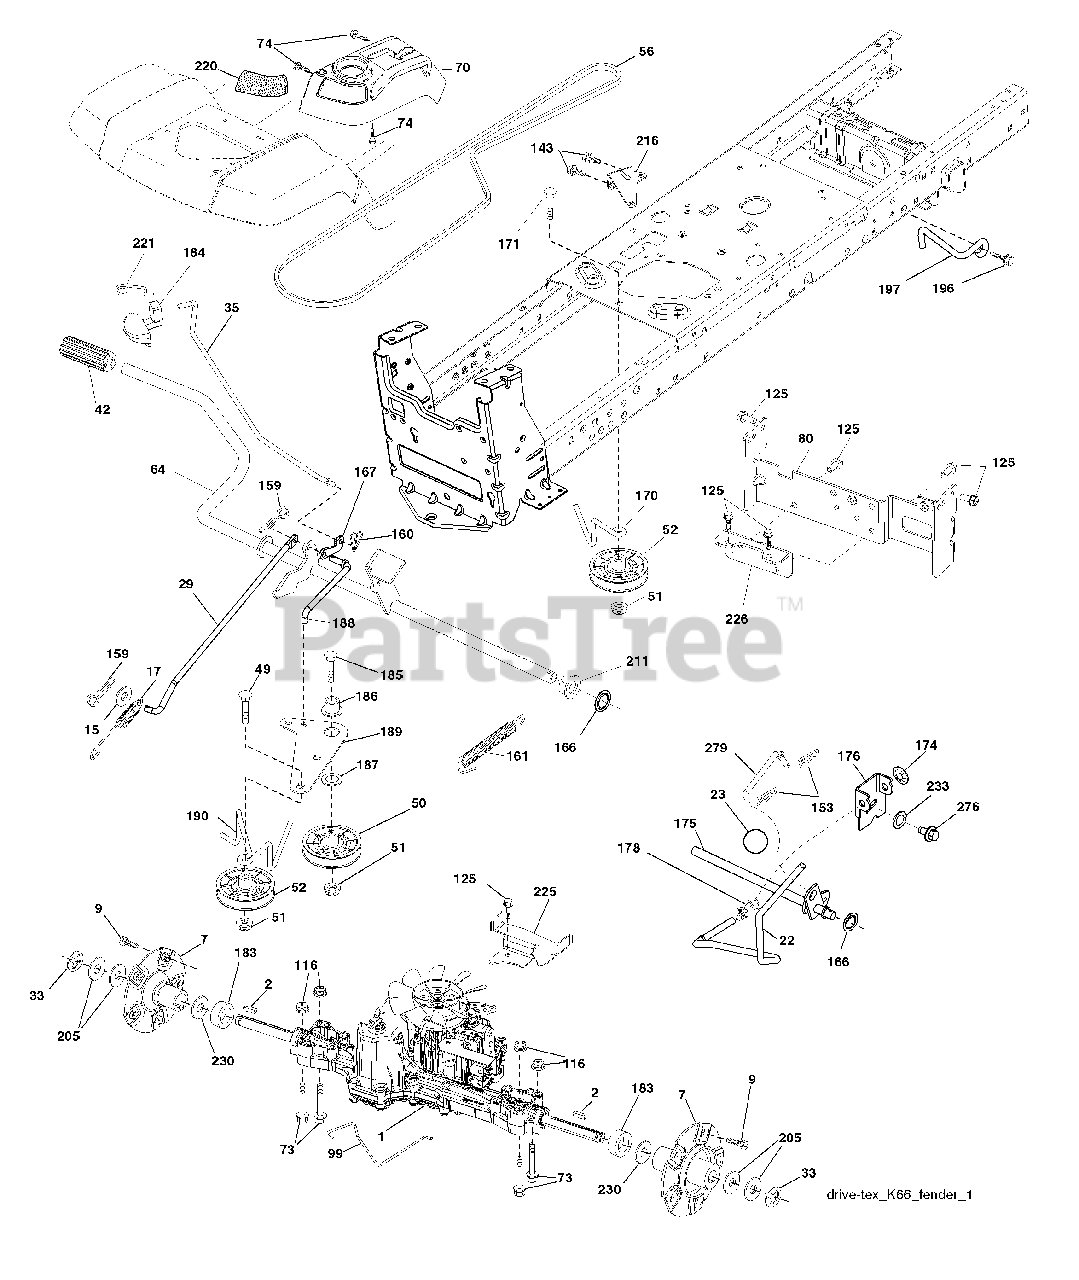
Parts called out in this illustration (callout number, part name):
1	Transaxle, TuffTorq K66
7	Hub Asm. Wheel
9	Bolt Hub Wheel
15	Washer 13/32 x 13/16 x 16 Ga.
17	Spring, Brake
23	Knob Deluxe 1/2-13 unc
29	Rod, Brake
35	Rod, Brake, Park
42	Cover, Foot Pedal
50	Pulley Idler Flat
51	Lock Nut 3/8-16
52	Idler V-Groove 910" Offset
56	V-Belt, Drive
64	Shaft Asm. Pedal Brake Control
70	Console Asm.
73	Bolt Hex Flghd 5/16-18 Gr. 5
74	Screw Hx Wsh Hi-Lo 1/4 x 1/2 unc
80	Strap Torque
99	Rod Bypass
116	Nut Lock Hex Flange 5/16-18
125	Screw 5/16-18 x 3/4
143	Screw 5/16-18 x 1/2
153	Retainer Spring
159	Pin Cotter 1/8 x 3/4
160	Retainer Clip
161	Spring, Return, Clutch
166	Nut Push .625
167	Latch Brake Parking
170	Keeper Belt Centerspan
175	Shaft Asm. Shift
176	Arm Clevis Rod Shift
178	Spring Shift
183	Spacer Axle
184	Handle Parking Brake
186	Spacer Retainer
187	Washer
188	Link Clutch Ground Drive
189	Bellcrank Ground Drive
190	Keeper Bellcrank Ground Drive
196	Screw 3/8-16 x 1
197	Bracket Clutch Anti-Rotation
205	Washer 1 1/32 x 1 5/8 x 16 Ga.
211	Bearing Nylon
216	Bracket Pulley Idler
220	Reflector RH
221	Retainer Spring Clip Handle
225	Keeper Belt Trans.
226	Bracket Mount Torque
230	Hardened Washer
233	Washer Serrated
276	Bolt Fin Hex 7/16-14 x 1 Gr. 5
279	Link Asm. Shift
